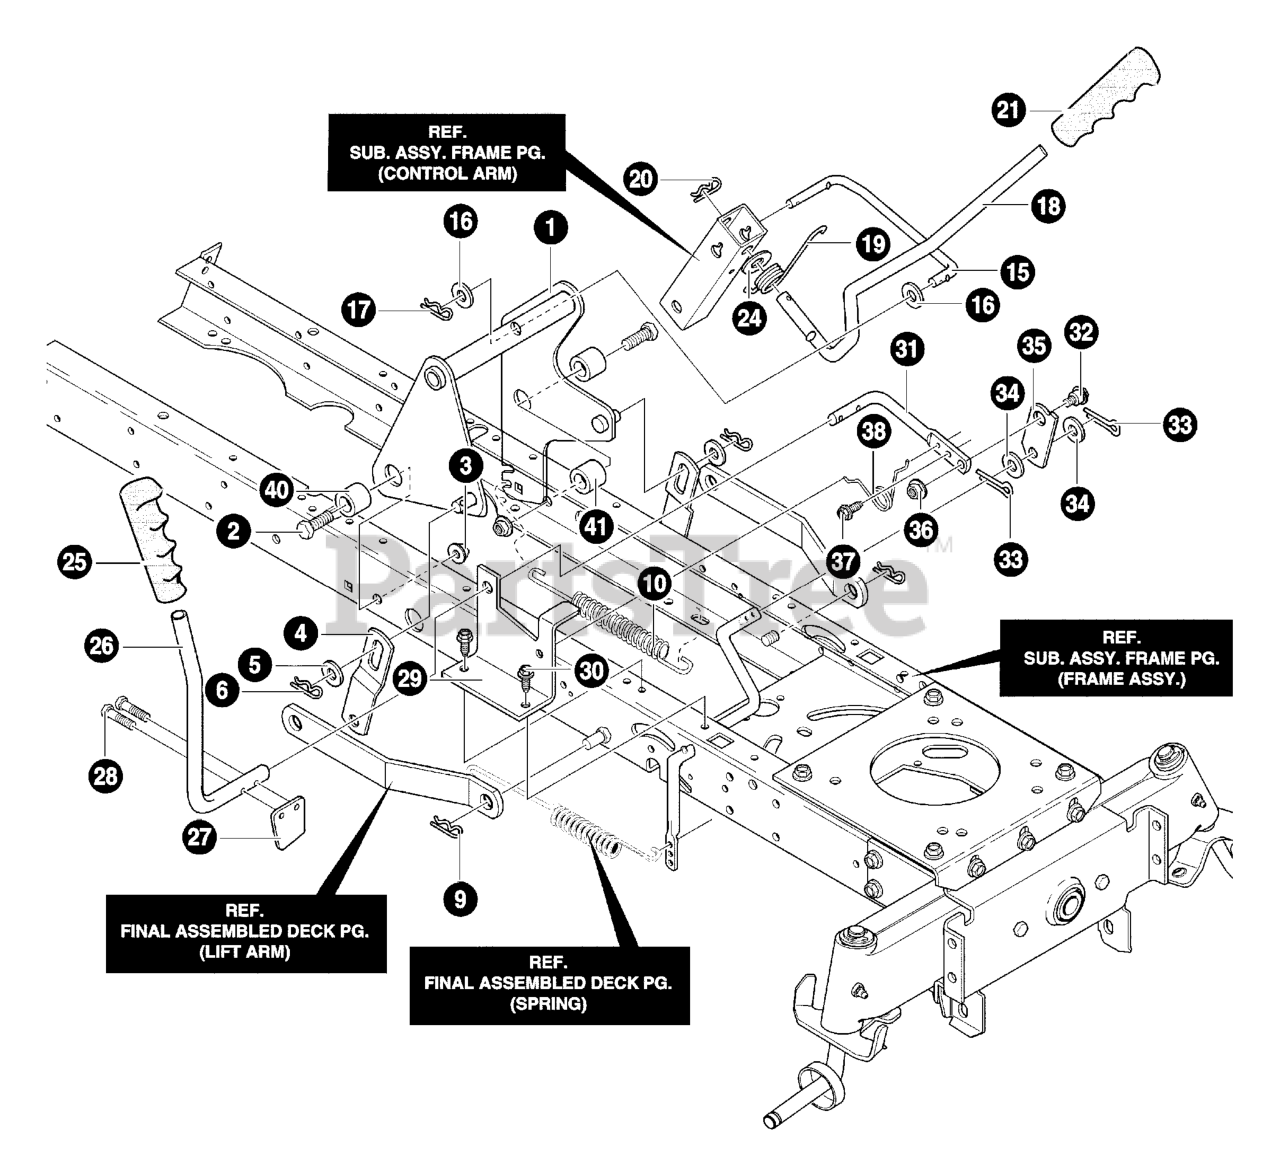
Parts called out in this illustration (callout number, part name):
1	ASM., LIFT ARM
2	SCREW, 1/2-13X1.50
3	NUT, 1/2-13 LOCK
4	BRACKET, LIFT LINK
5	WASHER, FLAT
6	PIN, HAIR
9	PIN, HAIR
10	SPRING, EXTENSION
15	LINK-LIFT HANDLE
16	WASHER, FLAT
17	PIN, HAIR
18	ZINC HANDLE, LIFT
19	TORSION SPRING
20	PIN, HAIR
21	GRIP, LIFT
24	WASHER, FLAT
25	Grip, PTO
26	PTO HANDLE
27	ZINC PADDLE, SWITCH
28	SCREW, THD FORM
29	BRACKET, PTO
30	SCREW, 5/16-18 x 0.50
31	ZINC LEVER, PTO
32	BOLT, .50X.75 HHSH 3/8-16
33	PIN, HAIR
34	WASHER, FLAT
35	ZINC LINK PTO
36	NUT, 3/8-16 HWDFLLK MACK
37	SCREW, 5/16-18 x 0.75
38	TORSION SPRING
40	SPACER
